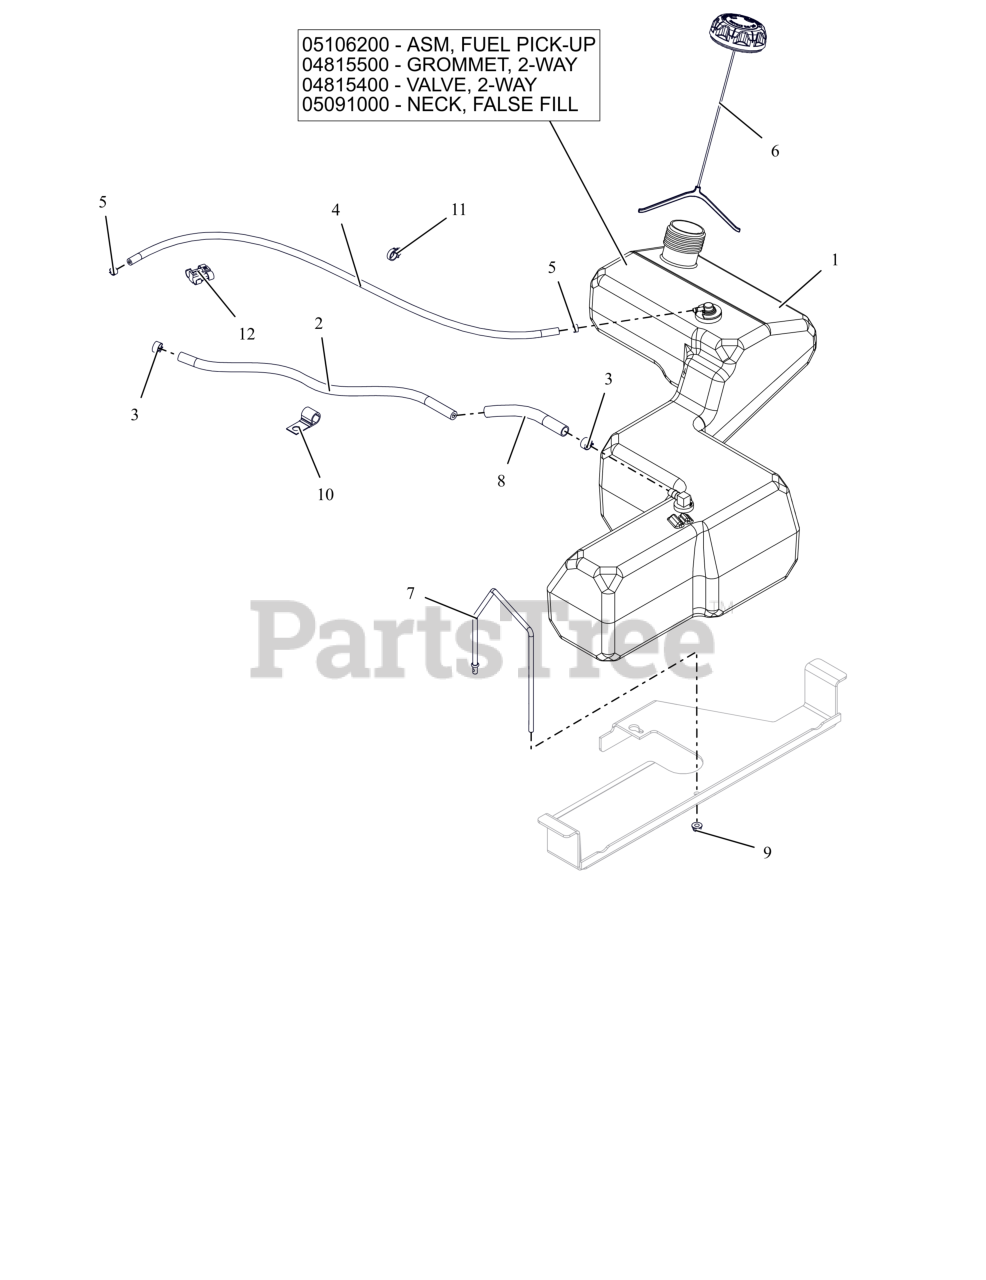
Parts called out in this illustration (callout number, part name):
1	ASM, FUEL TANK-IKON
1	ASM, IKON FUEL PICK-UP
1	GROMMET, 2-WAY
1	NECK, FALSE FILL-2017 IKON
2	HOSE, .25 LOW-PERM BULK GAS
3	CLAMP, FUEL LINE
4	HOSE, .188 LOW-PERM BULK GAS
5	CLAMP-HOSE, SPRING .188
6	CAP, FUEL VENT-IN 2.25" RATCH.
7	BRKT, FUEL TANK HOLD DOWN
8	WRAP, ANTIABRASION .5X.064WALL
9	NUT,NYL-FLG .25-20 GF ZCC
10	J-CLAMP
11	ROUTING CLIP (1/2" ID)
12	CLIP, T, .38-.50
